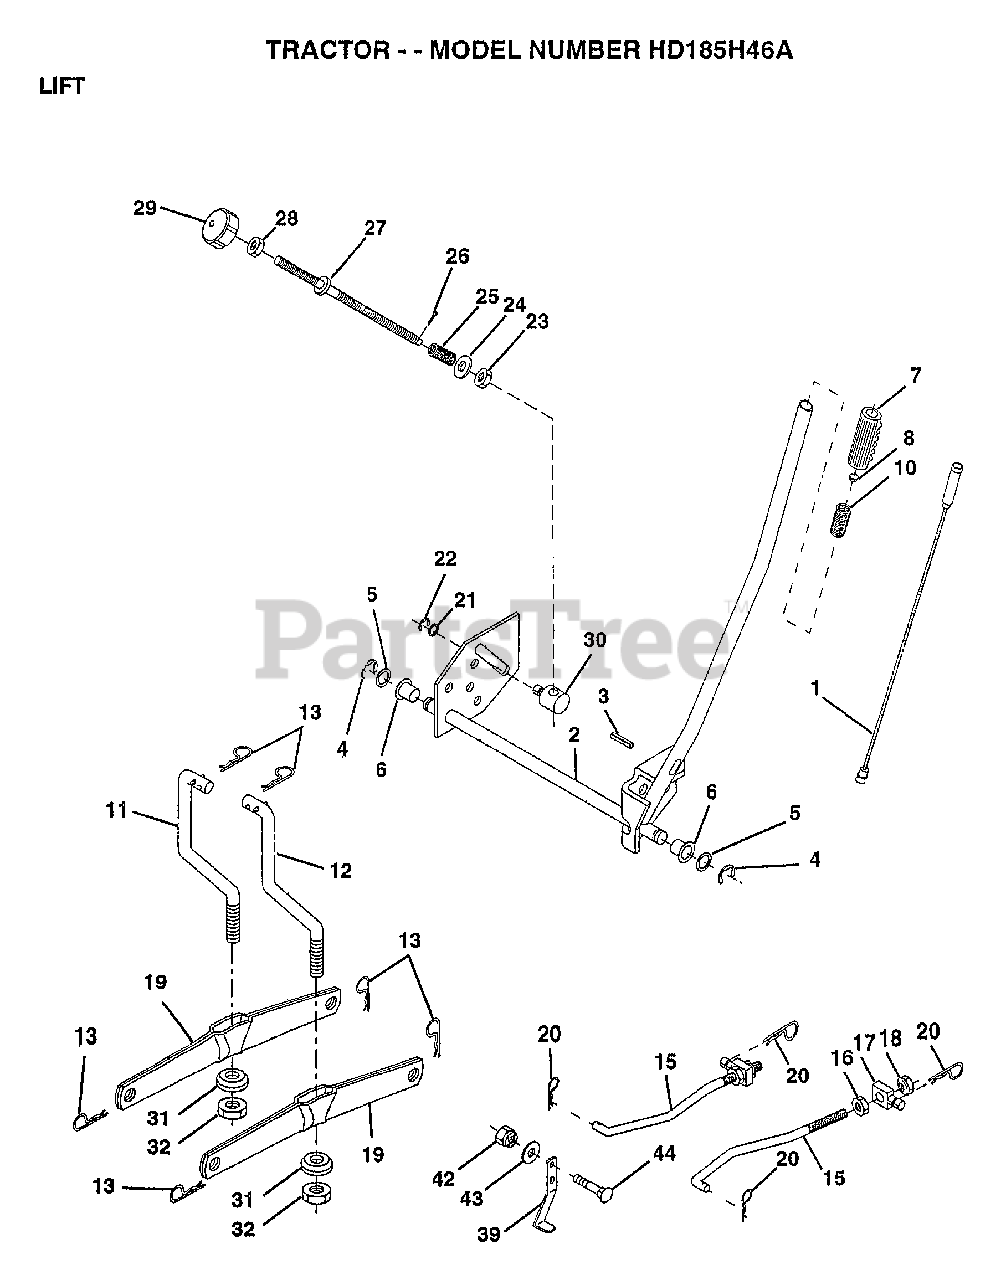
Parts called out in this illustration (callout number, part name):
1	LEVER ROD LT
2	SHAFT LIFT W/IND
6	"BOLT,HEX"
7	GRIP
10	SPRING T
11	LINK.LIFT.LH.GTV
12	LINK.LIFT.RH.GTV.
13	RETAINER RING
15	LINK.FRONT
16	NUT
17	TRUNION
18	NUT, LOCK W/WSH 1/2-13
19	ARM SUSP REAR
20	RETAINER RING
23	NUT T
25	SPRING T
26	PIN, COTTER 3/32 X 1/2
29	KNOB INF 3/8-16
30	TRUNNION
31	BEARING PVT LH
32	NUT.CROWNLOCK.3/8
39	STOP.OVER.CENTER
43	WASHER GT
44	BOLT CARRIAGE 3/8-16 X 1.00
46	E-RING
47	WASHER
49	NUT.HXFLG.LOCK.
50	NUT PUSH M
